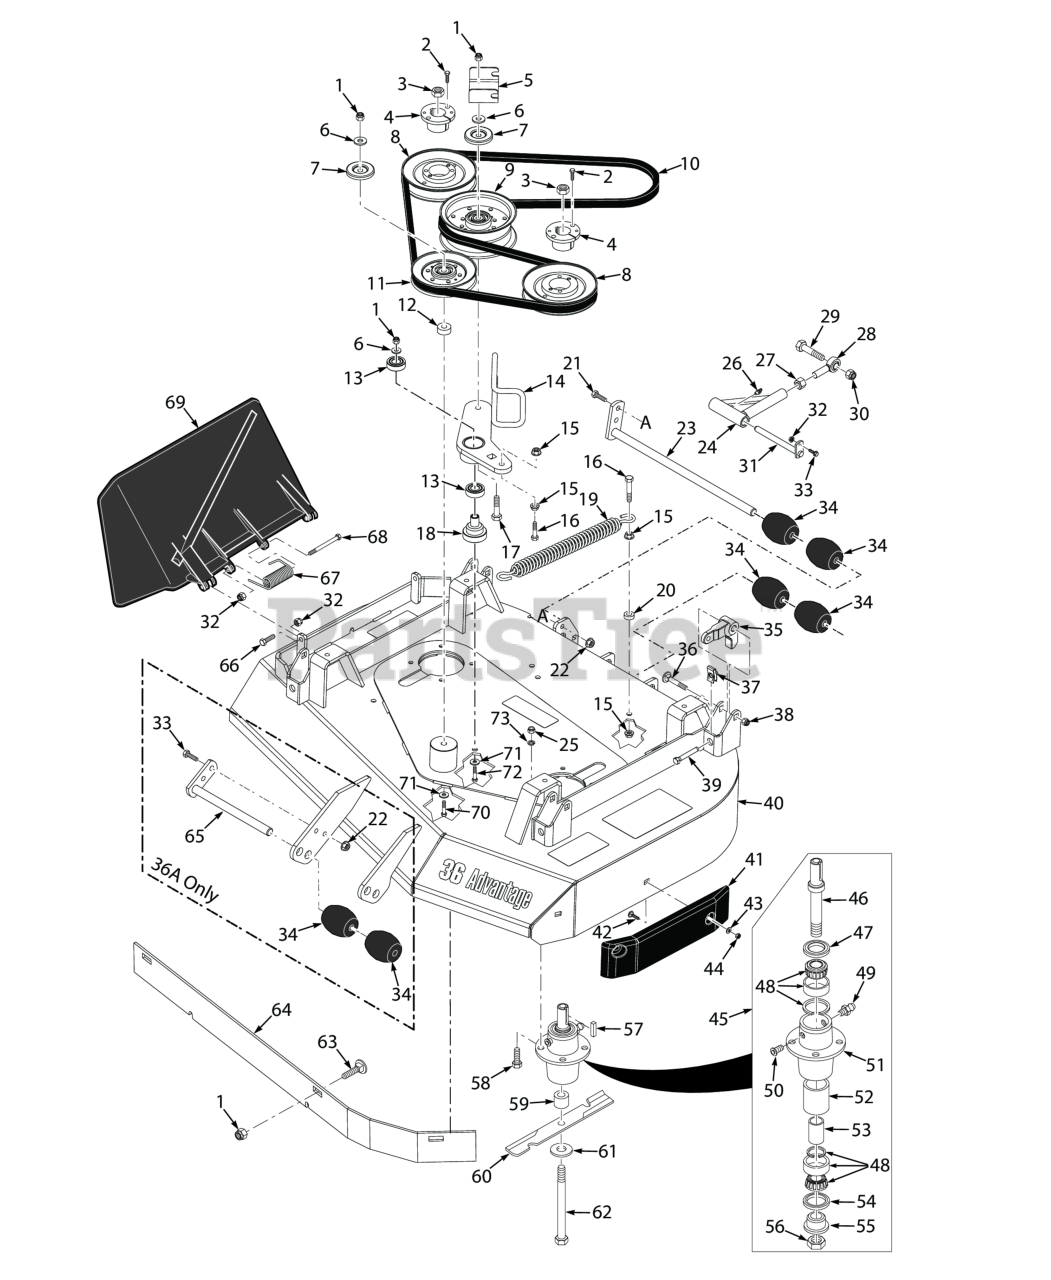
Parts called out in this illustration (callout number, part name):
1	HEX NUT, ELASTIC STOP LOCK, 3/8-16
2	Bolt, Hex Head 1/4-20 x 1" Grade 8 Black
3	Hex Locknut, Elastic Stop, 3/8-16
4	Hub, Tapered 1-1/8" Bore
5	Bracket, Belt Guide
6	Flatwasher, 3/8 (.391 x .938 x .105 HD) Grade 8
7	Quick Pin, 5/16" Dia.
8	Pulley, 5.73 OD Tapered Bore
9	Pulley, Idler 5" Dia.
10	Belt, Cutter Deck
11	IDLER PULLEY, "V" GROOVE
12	SPACER, J PULL ROD
13	BEARINGS, BALL, NEUTRAL RETURN
14	Idler Arm Assembly
15	NUT, 3/8-16 SERRATED FLANGE HEX HEAD
16	Bolt, Hex Head 3/8-16 x 1-1/2" Grade 8 Black
17	Capscrew, Hex Head 3/8-16 x 3.25"
18	Pivot, Idler
19	Spring, Cutter Deck
20	SPACER, IDLER
21	Bolt, Carriage 5/16-18x1" (large frame units only)
22	Nut, Flange Head Elastic Stop 5/16-18
23	Shaft Weldment
24	Pusharm Assembly, LH
25	Lock Nut, 5/16-18 Elastic Stop Grade 8
26	Grease Fitting, 90 Degree
27	Nut, Hex Head 5/8-18 UNF
28	Rod End, 5/8" Male RH Thread
29	BOLT, HEX HEAD 5/8-11 X 4-1/2"
30	HEX LOCKNUT, ELASTIC STOP, 5/8-11
31	Shaft Weldment, Pusharm Mounting
32	HEX NUT, ELASTIC STOP LOCK, 5/16-18
33	Bolt, Heax Head 5/16-18 x 1" (48V / 52V)
34	Wheel, Anti-Scalp
35	Lever, Deck Level
36	Bolt, Carriage 7/16-14 x 2-1/4"
37	U-Nut, 3/8-16 (short)
38	HEX LOCKNUT, ELASTIC STOP, 7/16-14
39	Bolt, Hex Head 3/8-16 x 2-1/2" Soecial Lock
40	Cutter Deck w/Decals
41	Pad, Deck Wear
42	Bolt, 5/16-18 x .75 RHSN Carriage
43	Flatwasher, 5/16-.344 x .688 x .065 (48V / 52V)
44	Nut, Center Lock, 5/16-18(32)
45	Spindle Assembly
46	Spindle Shaft, Tapered Brng
47	SEAL, 2.00 O.D. X 1.50 BORE
48	Tapered Bearing Set (Two Bearings W/Race)
49	GREASE FITTING, STR. 1/4-28 SELF TAP.
50	RELIEF FITTING, TAPERED BEARING SPINDLE
51	Housing, Spindle
52	Spacer, Outside, Cutter Spindle
53	SLEEVE, CUTTER SPINDLE
54	Seal, 2.00" O.D. x 1.625" Bore
55	SPINDLE BUSHING, BOTTOM
56	Nut , Spec ial 1 -1/ 1 6 - 1 8
57	Key, 1/4 x 1/4 x 2.0"
58	Bolt, Hex Head 5/16-18 x 1-3/4" Grade 8
59	Spacer, Spindle Bottom
60	Cutter Blade, 18" (52V)
61	Flatwasher, 5/8-.688 x 1-3/4 x .134 HD
62	BOLT, HEX HEAD, 5/8-11 X 9-1/2 GR.5
63	Carriage Bolt, 3/8-16 x 1.0"
64	Baffle, Flange - 36A
65	Shaft Weldment, Guide Roller
66	Bolt, Hex Head 5/16-18 x 1-1/2" - Front
67	Spring, Discharge Chute
68	Bolt, 5/16-18 x 4-3/4" Hex Head
69	Discharge Chute Advantage - Small
70	Bolt, Hex Head 3/8-16 x 4-3/4"
71	Flatwasher, 3/8-.406 x 1-1-1/2 x 7 Gauge
72	Capscrew, Hex Head 3/8-16 x 3.25"
73	Lockwasher, 5/16 (.317 x .586 x .078) Helical Spring
